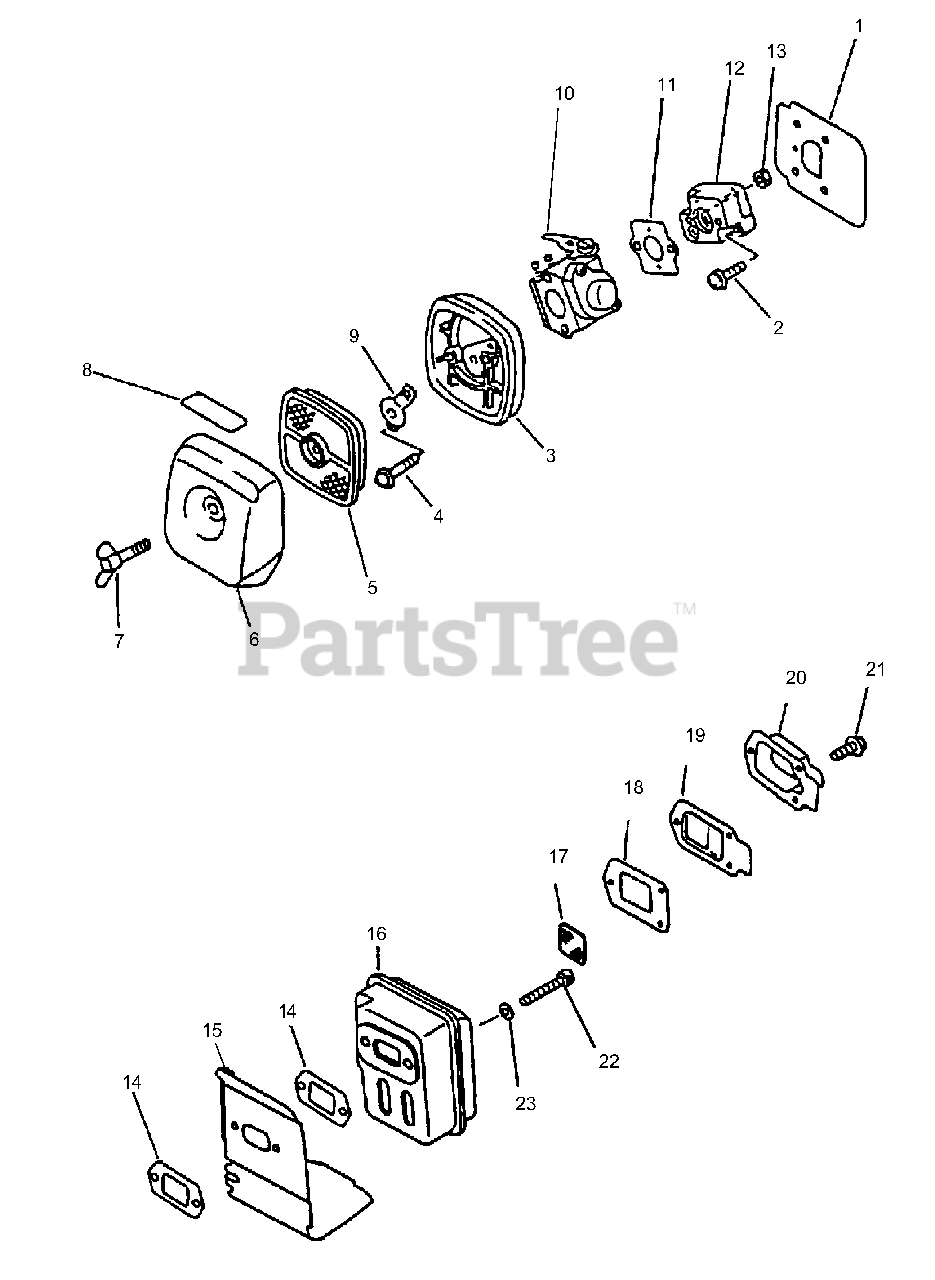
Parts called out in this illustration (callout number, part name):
1	HEAT SHIELD, INTAKE
2	SCREW 5×20
3	AIR FILTER CASE ASSY
4	SCREW 5×65
5	FILTER, AIR - SINGLE LAYER
6	COVER, AIR FILTER - GRAY
7	BOLT, WING 5×20
8	LABEL, CHOKE
9	PLATE, PREVENT
10	CARBURETOR - C1U-K47
10	CARBURETOR - C1U-K52
11	GASKET, INTAKE
12	INSULATOR, INTAKE
13	NUT M5
14	GASKET, EXHAUST
15	COVER, EXHAUST
17	SCREEN, SPARK ARRESTER
18	GASKET, EXHAUST
19	GUIDE, EXHAUST
20	GUIDE, EXHAUST - INNER
21	SCREW 4×10
22	BOLT 5×55
23	WASHER, FLAT 5.5×10×0.8
